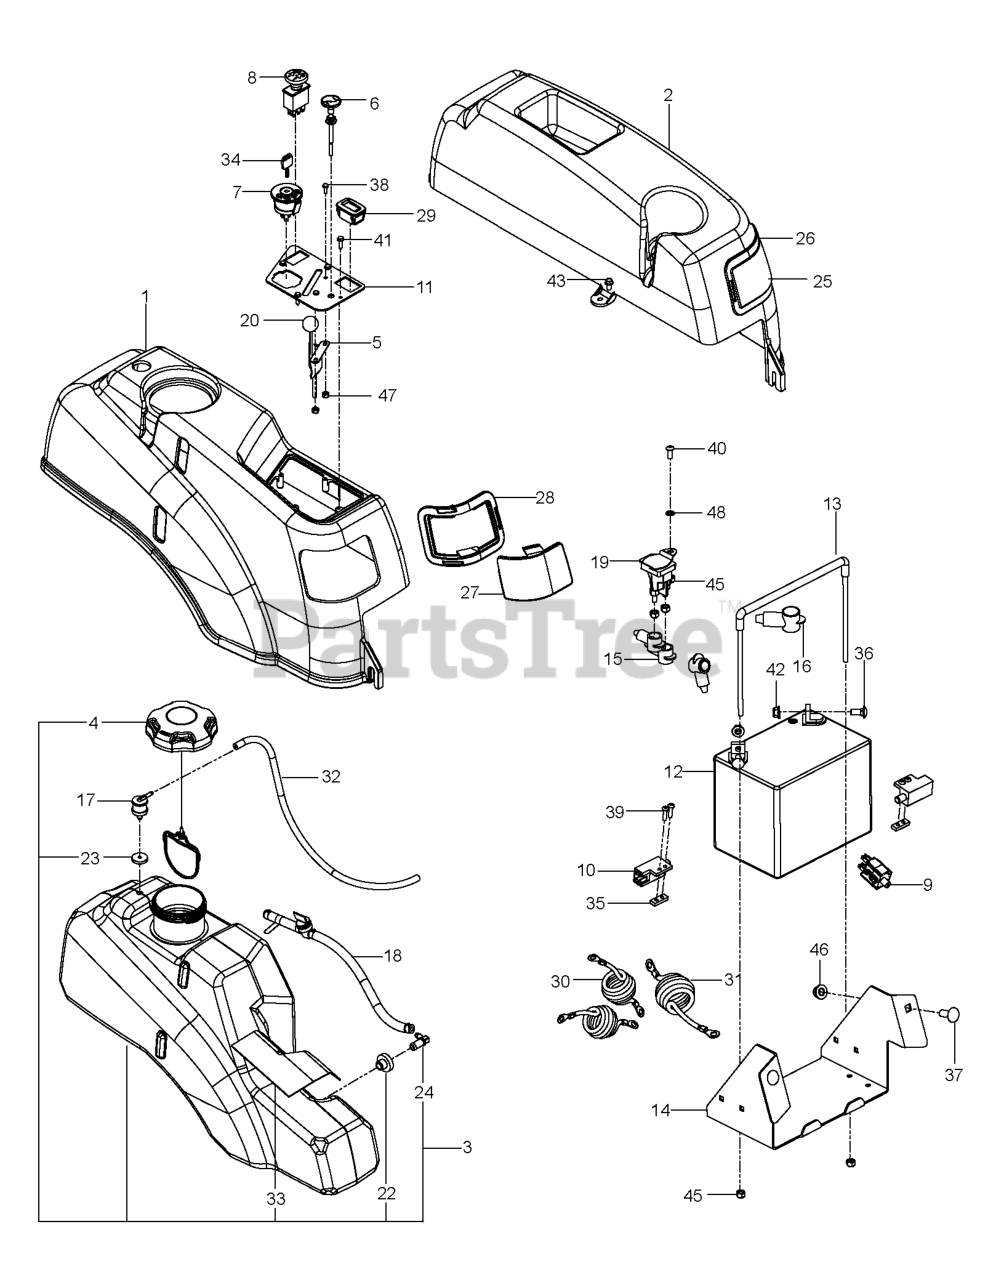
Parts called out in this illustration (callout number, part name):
1	FENDER RT, GRAY
2	FENDER, LT
3	TANK.FUEL.ASSEMBLY.LARGE
4	CAP, FUEL
5	THROTTLE CABLE
6	CHOKE CABLE
7	RP IGNITION SWITCH
8	RP SWITCH.PTO.8.TERMINAL.RED
9	SWITCH, BRAKE 3P
10	SWITCH INTERLOCKT
11	CONTROL PLATE RZ STD X431
12	BATTERY, 12 V 330 AMP
13	BATTERY TIE DOWN ASSEMBLY
14	BOX, BATTERY, BLACK
15	TERMINAL COVER-SM
17	VALVE.FUEL.CHECK
18	FUEL LINE ASSY
19	SOLENOID.W/BRASS.PLUNGER
20	KNOB.ROUND.BALL.BLACK
22	RUBBER GROMMET
23	GROMMET, CHECK VALVE
24	STEM, FUEL TANK
25	LENS, COLORED LEFT
26	LEFT HEADLIGHT RIM GREY
27	LENS, COLORED RIGHT
28	RT HEADLIGHT RIM GREY
29	RP.GUAGE.SRVCMNDR.HRMTR.
30	CABLE POSITIVE, LONG
31	BATTERY CABLE, NEGATIVE
32	HOSE, FUEL, 3/16" X 20"
33	SHIELD, HEAT
34	KEY MLD GEN DELTA
35	PLATE NUT ZTR
36	BOLT 5/16C X 3/4" CARRIAGE
37	RHSNB 3/8C X 1
38	HCS #10-24 X 1/2
39	SCR #10-24 X .75 SKT HD BLK
40	SCR 1/4-20 X 5/8 BTN SKT HD ZD
41	SCR #10-12X3/4 HEX WAS HD ZD
42	5/16-18 NYLOC FLANGE NUT
43	BOLT 1/4-20 X 1/2 HWST
45	NUT.1/4-20.HEX.NYLOC.ZD
46	NUT 3/8-16 HEX FLG NYLOC ZD
47	NUT 10-24 NYLOC
48	WASHER 1/4 INT TOOTH
